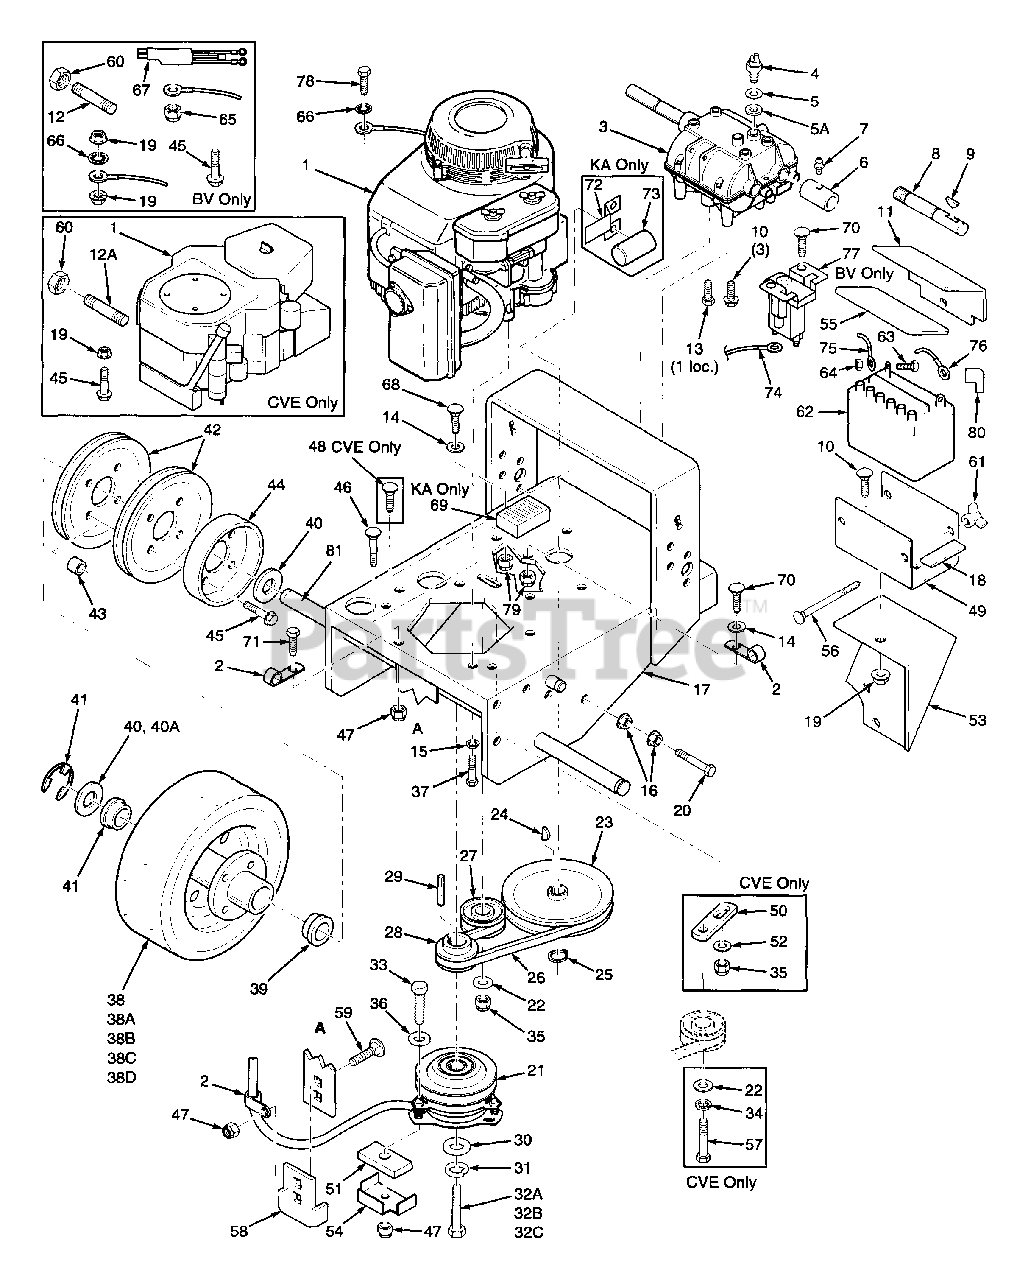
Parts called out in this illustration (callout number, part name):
1	Engine, 16HP Briggs Vanguard
1	Engine, 16HP BVE
1	Engine, 18HP Briggs Vanguard
2	Cable Clamp
3	Transmission, 5-speed
4	Neutral Safety Switch
5	Fibre Washer, thin
5A	Fibre Washer, thick
6	Coupler, Jackshaft
7	Grease Fitting, straight 1/4-28
8	Jackshaft
9	Key, Hi-Pro #9
10	Bolt, 5/16-18 X 3/4" Carriage
11	Battery Cover
12	Oil Drain Extension 5-1/4"
12A	Oil Drain Extension 4-3/4"
13	Bolt, 5/16-18 X 3/4" Hex Head
14	Flat Washer 1/4" (.312 X .75 X .065)
15	Lock Wshr. 5/16"
16	Nut, 3/8-16 Serrated Flange
17	Engine Deck
18	Rubber Pad
19	Nut, 5/16-18 Serrated Flange
20	Bolt, 3/8-16 x 3-3/4" Hex Head
21	Electric Clutch
22	Washer, 3/8" (.391 x .938 x .105)
23	Pulley, Transmission Input
24	Key, Woodruff #9
25	Retaining Ring, 5/8" Ext, Basic
26	Belt, Transmission Drive
27	Idler Pulley, Transmission
28	Pulley, Traction Drive
29	Key, 1/4 x 1/4 x 3/4"
30	Flat Washer, 7/16" Special
31	Lock Washer, 7/16"
32A	Bolt, 7/16-20 x 2-1/2" Hex Head
32B	Bolt, 7/16-20 x 1-3/4" Hex Head
32C	Cpsrw, M10-1.5 x 60 Metric Hex Hd
33	Bolt, 5/16-18 x 1-1/4" Hex Head
34	Lockwasher, Spring 3/8"
35	Nut, 3/8-16 Elastic Stop
36	Flat Washer, 5/16"
37	Bolt, M8-1.25 x M25 Metric Hex Hd
38	Wheel Assembly
38A	Tire, 13 x 6.50-6, 2-ply
38B	Rim & Bearing Assembly
38C	Tire, 13 x 5.00-6 2-ply
38D	Rim Assembly
39	Wheel Brng. NWC (OD 1.984-1.980)
40	Washer, 1-1/16 x 1-3/4 x 12 ga
40A	Washer, 1-1/16 x 1-1/2 x 18 ga
41	Retaining Ring, 1" Ext - "E"
42	Pulley, Wheel Drive
43	Spacer, Wheel Pulley
44	Brake Drum
45	Bolt, 5/16-18 x 1-1/2" Serrated Flange
46	Bolt, 3/8-16 x 2" Carriage
47	Nut, 5/16-18 Elastic Stop
48	Bolt, 3/8-16 x 1-1/4" Carriage
49	Battery Box
50	Bracket, Idler Pulley
51	Rubber Pad, Clutch Stop
52	Washer, 13/32 x 1-1/2 x 7 ga
53	Battery Support Weldment
54	Backing Plate
55	Battery Cover Pad
56	Bolt, 1/4-20 x 6" Carriage
57	Bolt, 3/8-16 x 1-3/4" Hex Head
58	Anti Rotation Bracket
59	Bolt, 5/16-18 x 1" Carriage
60	Pipe Cap
61	Wing Nut, 1/4-20
62	Battery
63	Bolt, 1/4-20 x 1/2" Hex Head
64	Nut, 1/4-20
65	Nut, 1/4-20 Elastic Stop
66	Lock Washer Internal Tooth
67	Wire Harness Adapter, Man Start
67	Wire Harness Adapter, Elec Start
68	Bolt, 1/4-20 x 1-1/4"
69	Rectifier
70	Bolt, 1/4-20 x 3/4" Carriage
71	Bolt, 5/16-18 x 1" Hex Head
72	Bracket, Capacitor
73	Condenser
74	Battery Cable, 18" Red
75	Battery Cable, 27" Black
75	Battery Cable, 36" Black
75	Battery Cable, 31" Black
76	Battery Cable, 31.5" Red
77	Starter Solenoid
78	Bolt, M8-1.25 x 1.0
79	Nut, 1/4-20 Elastic Stop
80	Rubber Boot
81A	Wheel Axle
81B	Wheel Axle
81C	Wheel Axle
